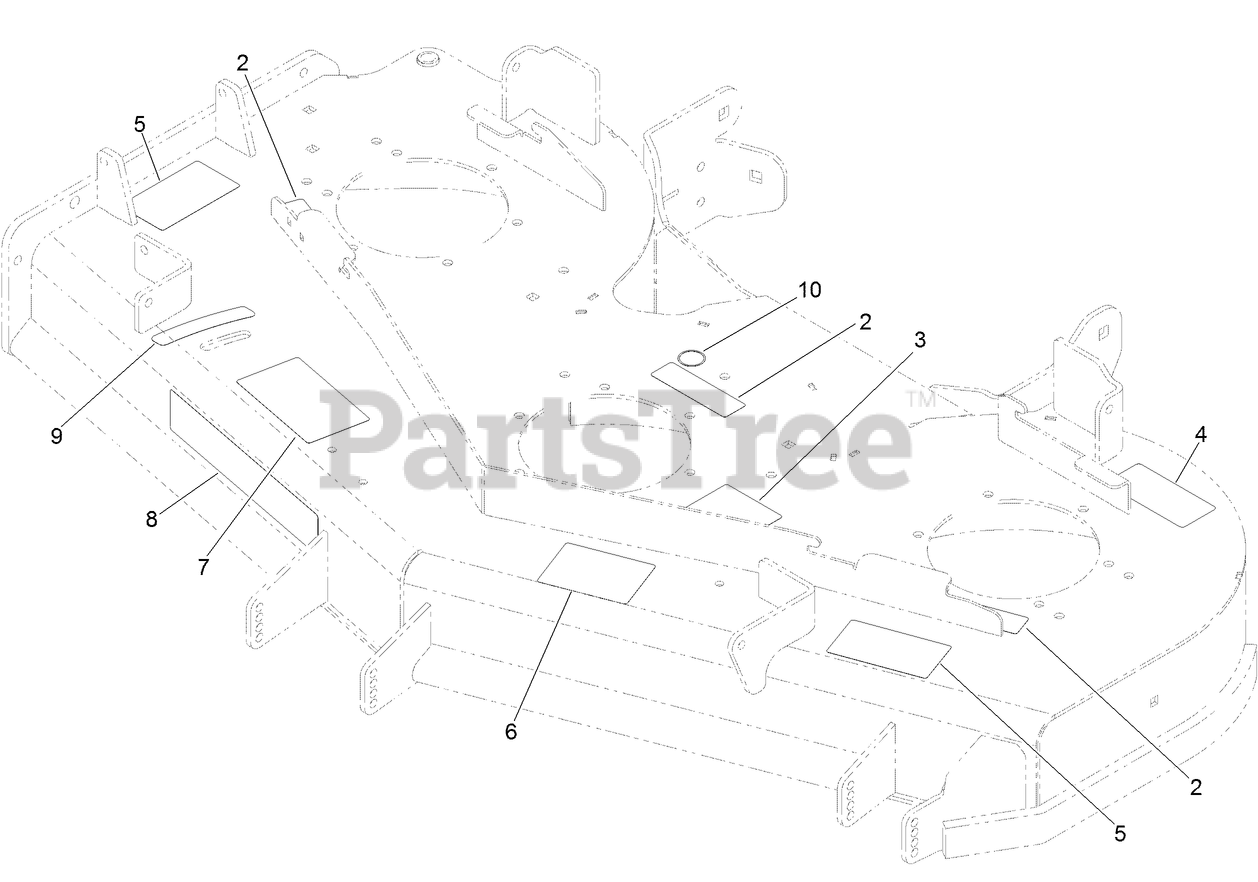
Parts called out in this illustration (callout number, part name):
2	DECAL-MISSING, COVER
3	DECAL-ROUTING, DECK BELT
4	DECAL-TORQUE, BLADE BOLT
5	DECAL-DANGER
6	DECAL-ANTI SCALP
7	DECAL-ADJUSTMENT, BAFFLE
9	DECAL-SETTING, BAFFLE
10	DECAL-GREASE
